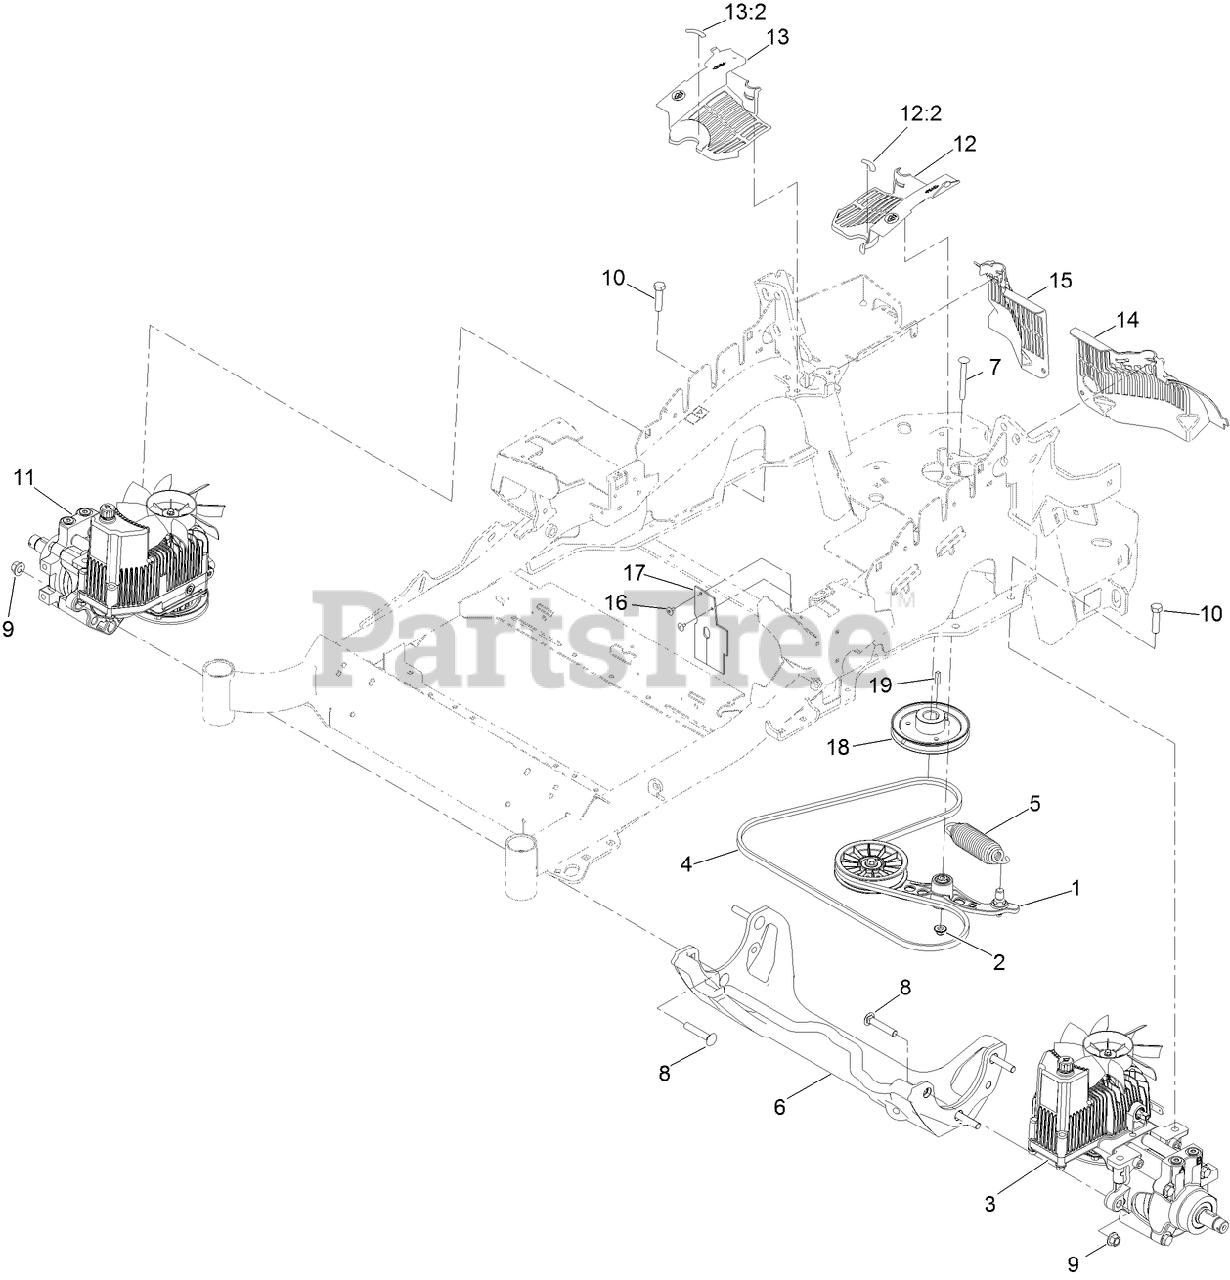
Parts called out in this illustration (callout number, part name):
1	PUMP IDLER ASM
2	NUT-FLANGE, NI
3	LH HYDRO ASM (12CC W/ CHECK)
4	BELT
5	SPRING-EXTENSION
6	CRADLE-HYDRO
7	BOLT-SHOULDER, CARRIAGE
8	SCREW-CARR
9	NUT-LOCK
10	SCREW-HH
11	RH HYDRO ASM (12CC W/ CHECK)
12	LH HYDRO GUARD ASM
12:2	DECAL-OIL, HYDRO
13	RH HYDRO GUARD ASM
13:2	DECAL-OIL, HYDRO
14	GUARD-HYDRO, REAR (LH)
15	GUARD-HYDRO, REAR (RH)
16	RIVET-POP
17	DEFLECTOR-AIR FLOW
18	SHEAVE
